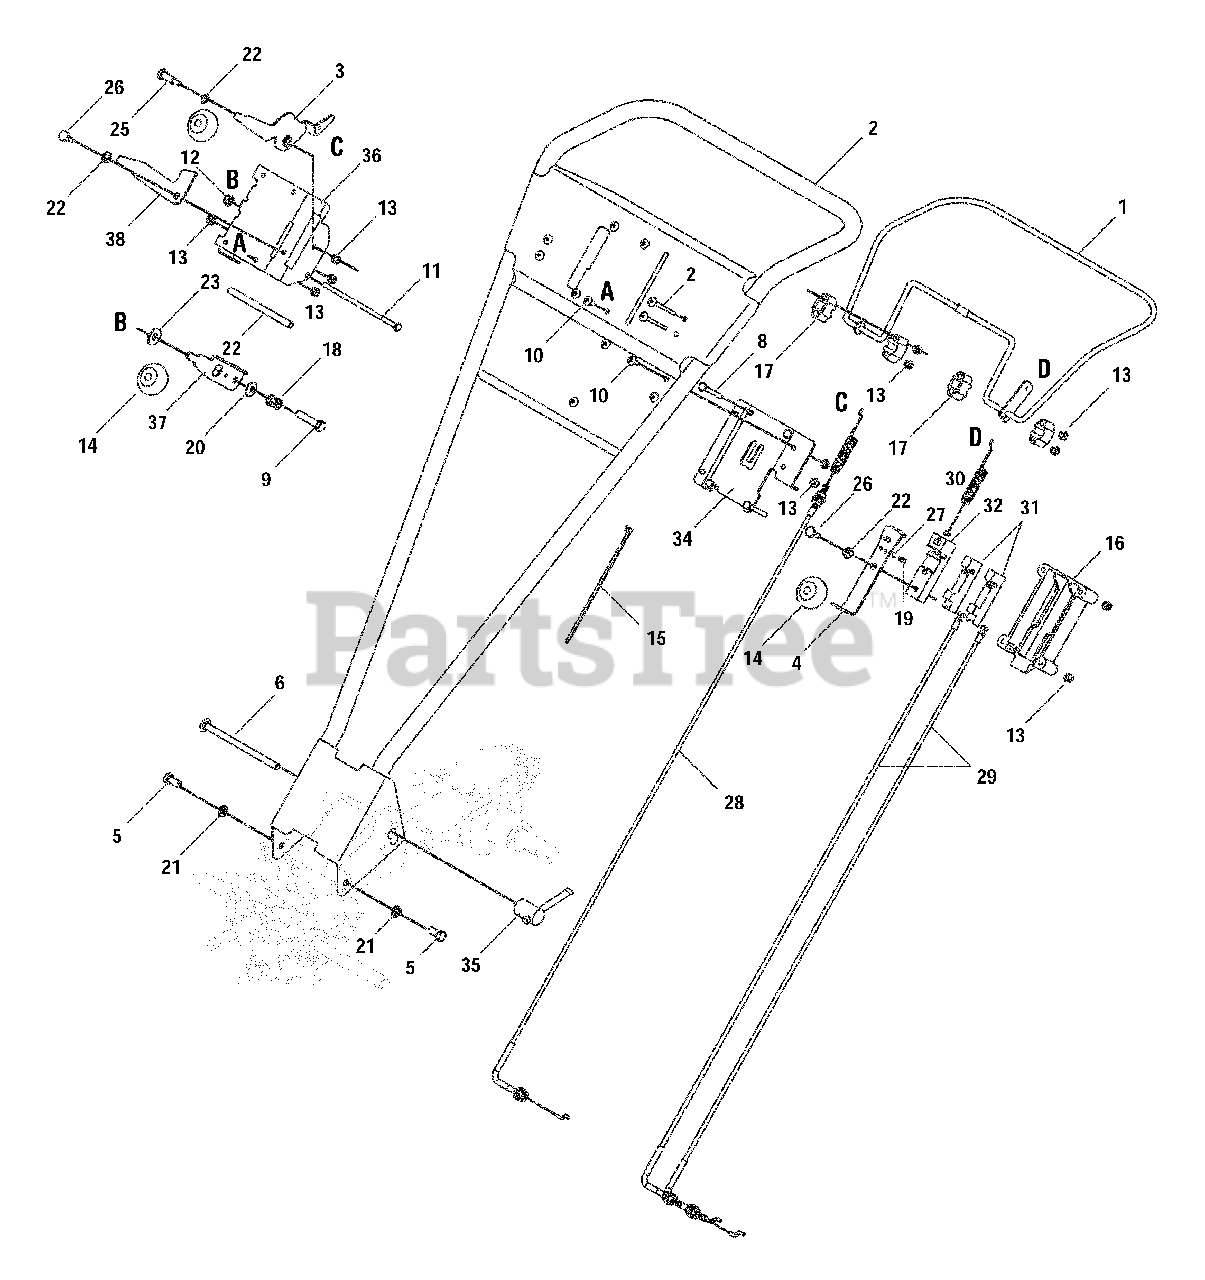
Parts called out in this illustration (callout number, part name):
1	Bail Assembly, Control, Wheel
2	Handle Assembly, Loop
3	Lever Assembly, Control, Tine
4	Lever Assembly, Pivot
5	Hex Screw, 3/8-16,.75, Gr5
6	Screw, Carriage, 3/8-16, 6.00, Gr5
7	Screw, Machine, 1/4-20, 2.500
8	Hex Screw, 1/4-20, 2.0, Gr5
9	Hex Screw, 3/8-24, 1.75, Gr5
10	Screw, Machine, 1/4-20, 0.625
11	Hex Screw, 1/4-20, 6.00, Gr5
12	Nut, Jam Lock, 3/8-24, Gr5, Nylon
13	Nut, Hex Lock, 1/4-20, Gr8, Nylon
14	Knob, Shift
15	Cable, Tie, 3/16 x.05 x 7.4
16	Box, Control, Select, Tine
17	Block, Mounting, Bail
18	Spring, Compression,.39x.60 x.88 Lg
19	Spring, Compression
20	Washer, Bell,.375 x.870 x.063
21	Washer, Lock, 3/8, Regular Duty
22	Washer, Wave,.390 x.625 x.016
23	Washer, Flat,.406 x 1.00 x.105
25	Screw, Shoulder,.373 x.830, 1/4-20
26	Screw, Shoulder,.373 x.180 x 1/4-20
27	Ball, Detent,.250
28	Cable, Clutch, Drive, Wheel
29	Cable, Clutch, Drive, Tine
30	Cable, Engagement, Tine
31	Block, Control, Select, Tine
32	Block, Control, Engage, Tine
33	Spacer,.270 x.375 x 5.00 Lg
34	Bracket, Mounting, Control
35	Crank, Adjustment, Handle
36	Bracket, Mounting, Control
37	Lever, Shift
38	Bracket, Pivot, Interlock
